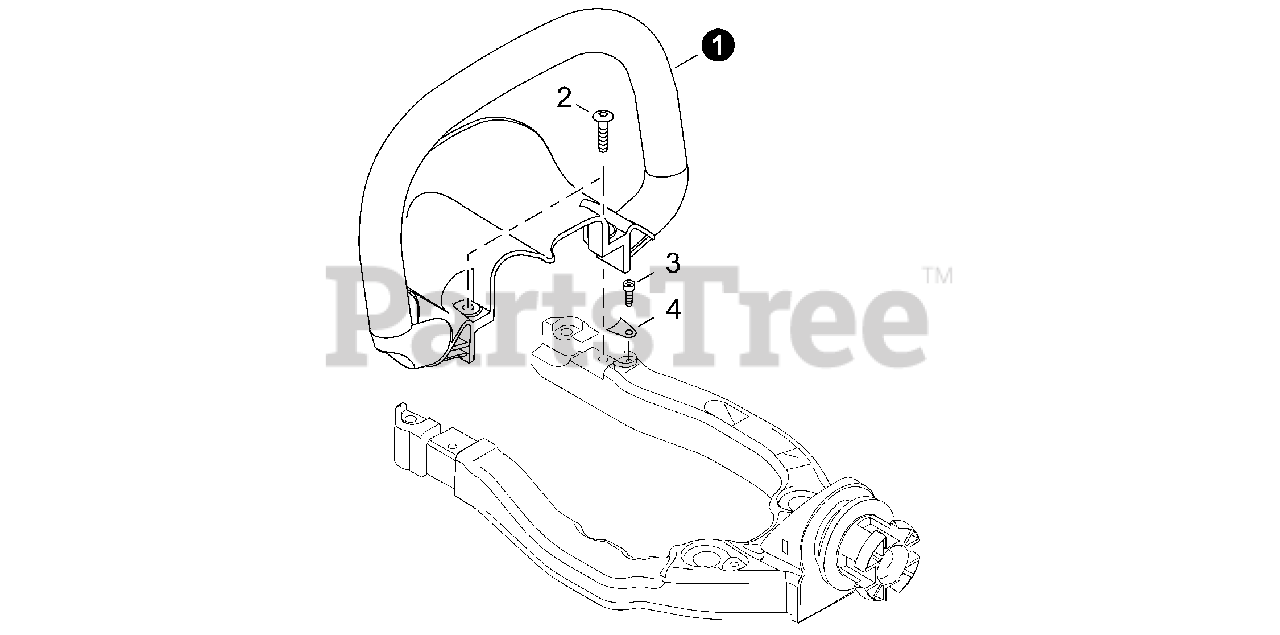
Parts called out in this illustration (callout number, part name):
1	HANDLE, FRONT
2	BOLT, TORX 6
3	BOLT, TORX 4×12
4	PLATE, EYE
